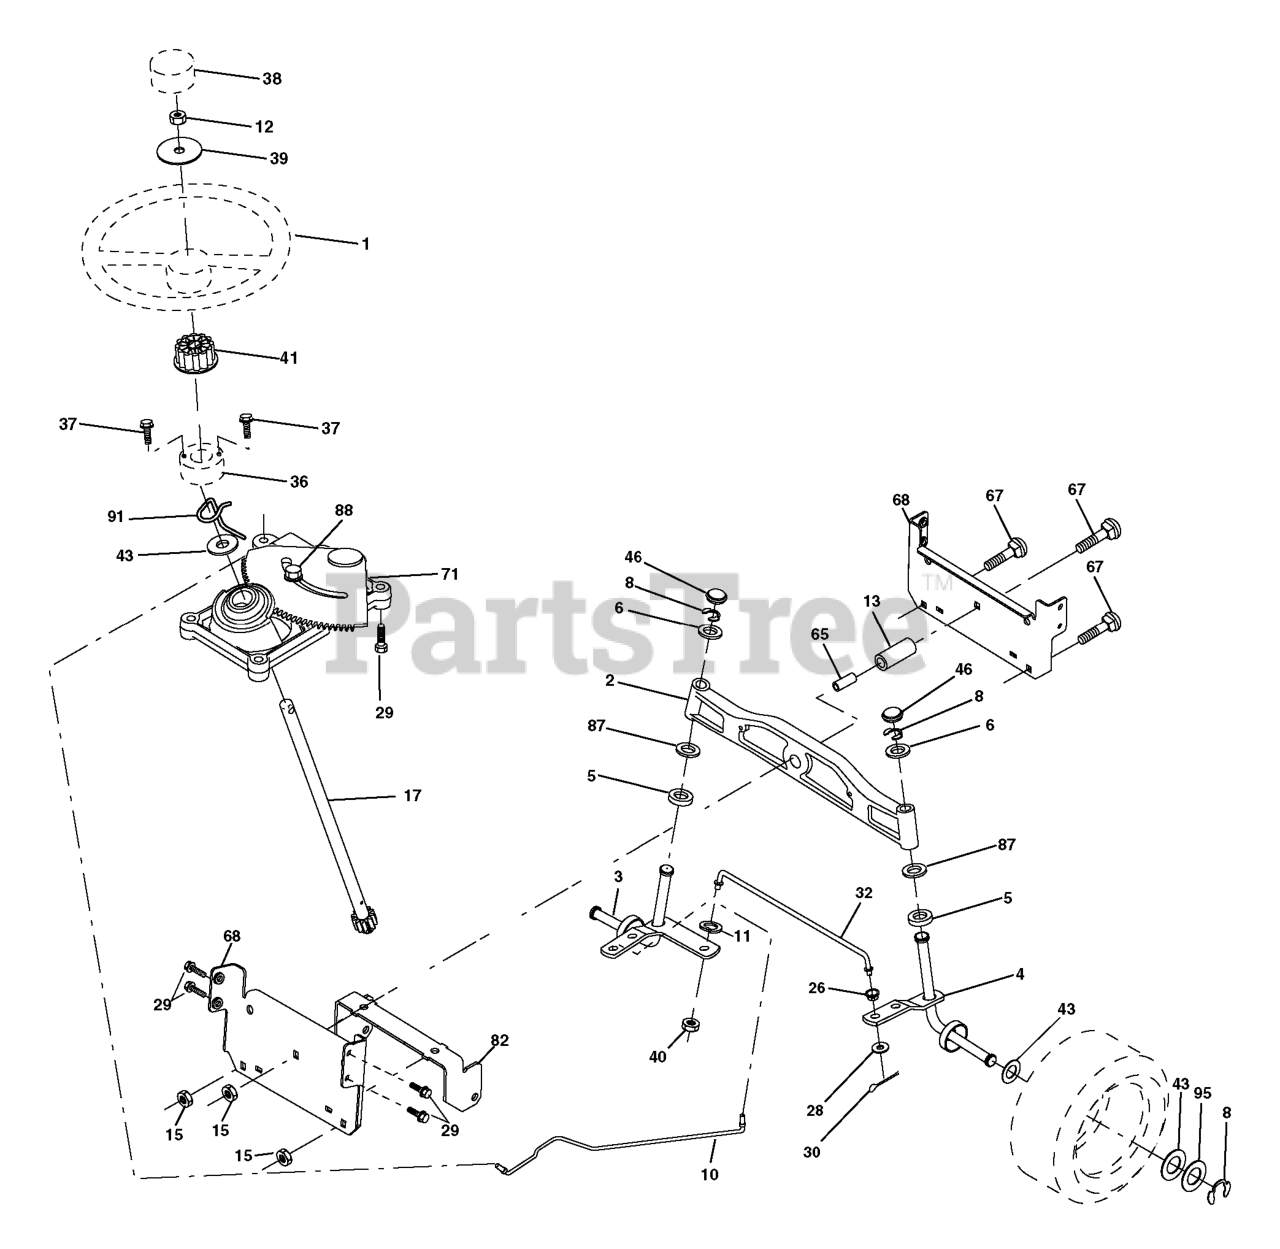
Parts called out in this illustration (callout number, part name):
1	WHEEL.STEERING.LEGEND2.GRY
2	AXLE ASSY FRONT
3	SPINDLE.ASM.LH.15"TIRES
4	SPINDLE.ASM.RH.15"TIRES
5	THRUST WASHER
10	DRAGLINK.15".TIRES.2001
11	WASHER, LOCK 3/8
12	NUT.HEX.1/2-20
13	TUBE, PIVOT AXLE
15	NUT
17	SHAFT ASM STRG
26	BUSHING.DRAGLINK (2 2)
28	WASHER
29	SCREW, 3/8-16X3/4
30	COTTER PIN
32	ROD.TIE.WIRE.FORM
36	BUSHING, STRG. BLK
37	SCREW.TT.#10-32X.5.3/8.FLANGE
38	INSERT.CAP.STRG.WH.GRAY
39	WASHER 9/16"ID, 2 3/8"OD
40	NUT CROWNLOCK 3/8-24
41	ADAPTER, WHEEL STNG..
46	CAP.SPINDLE.BLACK
65	SPACER BRACE AXLE
67	BOLT CARRIAGE
68	BRACE.AXLE.15"TIRES
71	STEERING ASM
82	BRACKET
87	WASHER, FLAT .781 X 1 1/2"
88	BOLT, SHOULDER 7/16-20
91	CLIP.STEERING
95	WASHER.HARDENED
